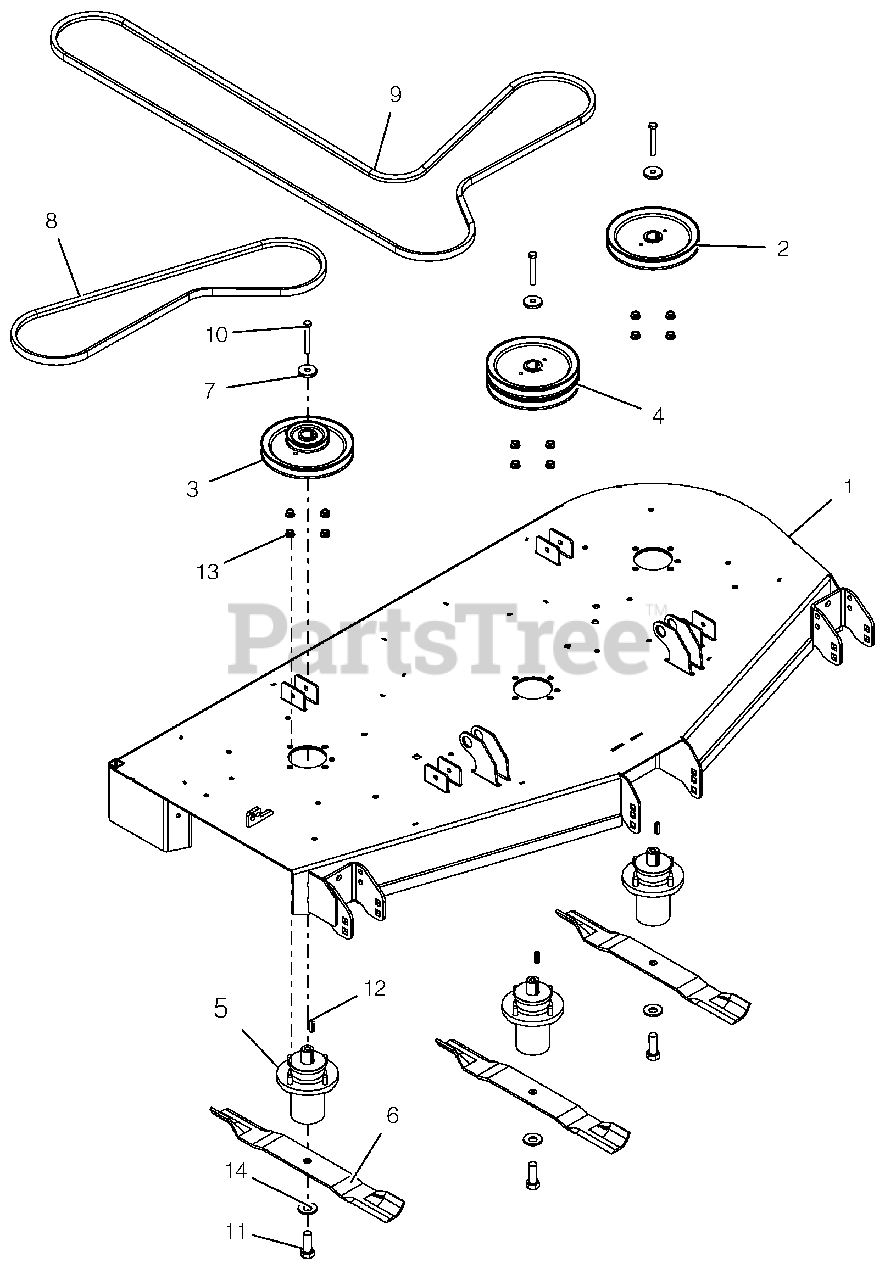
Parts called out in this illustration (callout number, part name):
1	KIT,DECK-60" W/DECALS-GRAVELY
2	PULLEY, V-7.50 OD X 1"ID
3	PULLEY, DOUBLE 1"ID X 7.50"OD & 3.50"OD (BLACK)
4	PULLEY, DOUBLE 1"X7.50"&7.50" (BLACK)
5	ASM, MAINT FREE SPINDLE ALUM
6	BLADE, 20.5"
7	RETAINER, SHEAVE
8	V-BELT, B-COGGED
9	V-BELT, HB SECTION
10	BLT-HEX .38-16X2.75 GR8 YWZC
11	BLT-HEX .62-18X1.75 GR8 YWZC
12	KEY, SQ .25X.25X1.00 RC 40-50
13	NUT-LK-CTR-FLG .38-16 YWZC
14	WSHR-BLVL .669X1.535X.138
